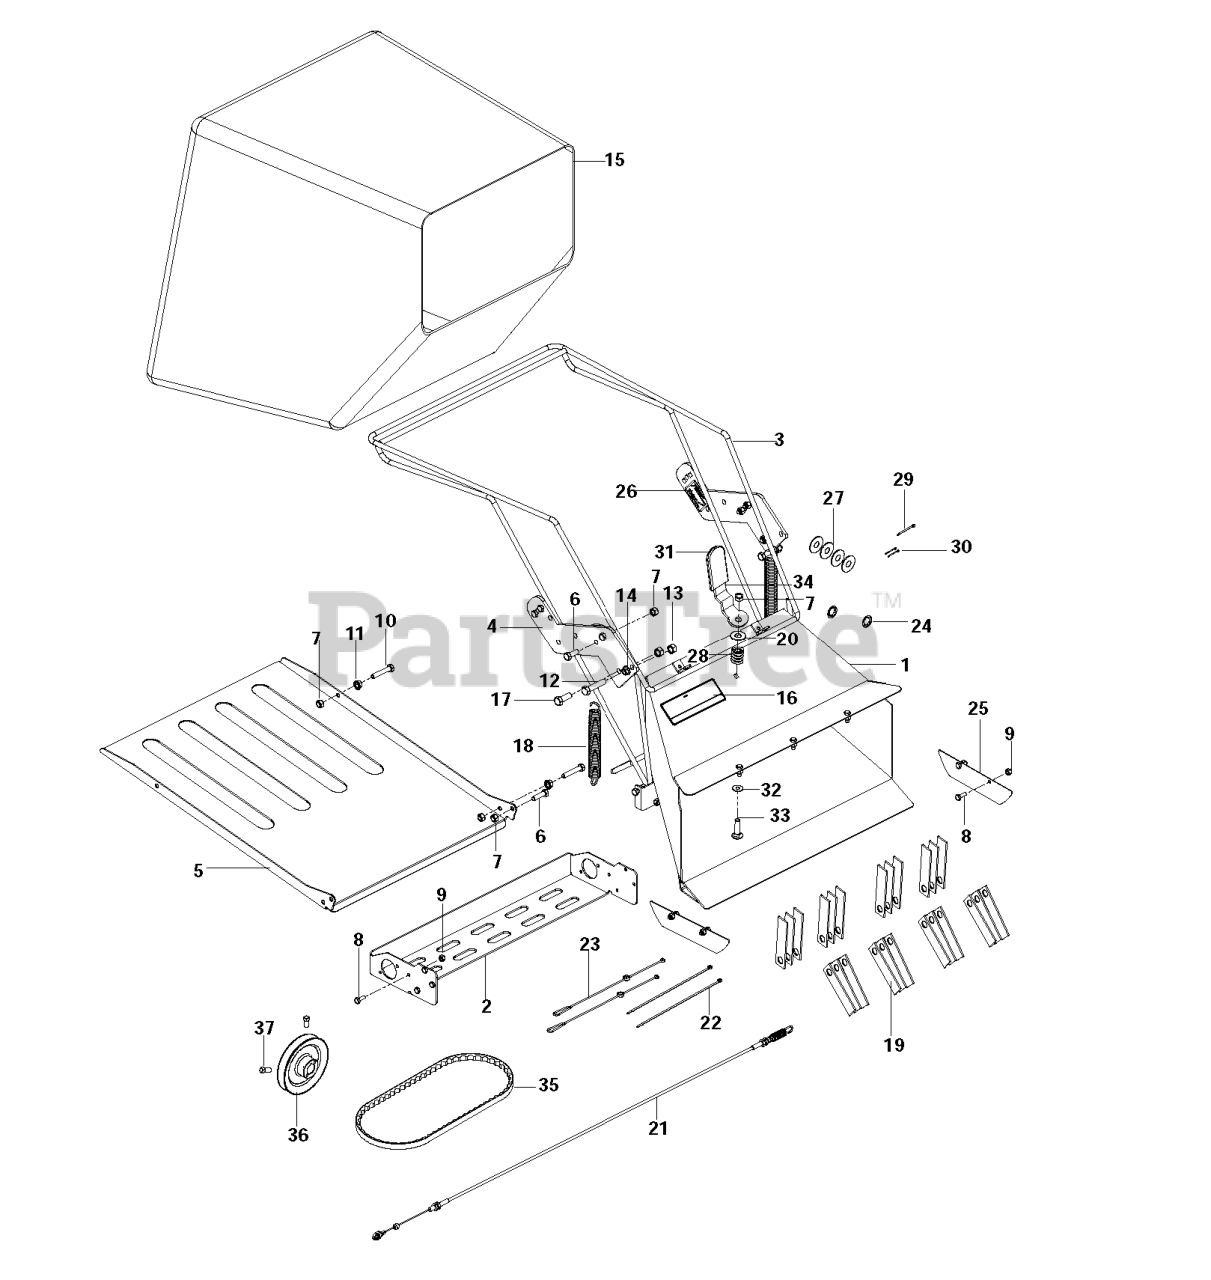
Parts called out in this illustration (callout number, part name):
1	CHUTE W/DECAL ORANGE
2	BAGGER TRAY
3	BAG FRAME, BLACK
4	EXTENDER GREY
5	SAFETY DOOR ORANGE
6	HCS 5/16C X 1
7	NUT 5/16 NYLOC
8	HCS 1/4C X 3/4 HCS
9	NUT.1/4-20.HEX.NYLOC.ZD
10	HCS 5/16C X 1 3/4
11	NUT 5/16C WHIZ
12	HCS 3/8C X 2
13	NUT 3/8-16 NYLOC
14	NUT 3/8C WHIZ
15	CATCHER BAG
16	DECAL, BAGGING GRAPHIC
17	HCS 3/8-16X1.GRD.5.ZD
18	SPRING BAGGER
20	WASHER 5/16 FLAT
21	CABLE 46.5" POWER RAKE
22	TIE, PLASTIC
24	NUT 5/8 PUSH
25	SIDESHIELD
26	DECAL, HANDLE PIN
27	WASHER 5/8 FLAT
28	COMPRESSION SPRING
29	COTTER PIN
30	COTTER PIN 3/32 X 3/4
32	WASHER 3/8 FLAT
33	RHSNB 5/16-18X1 3/4
35	BELT-COGGED
36	PULLEY, 4.5"
37	SCREW 5/16C X 5/8 SQ HEAD
